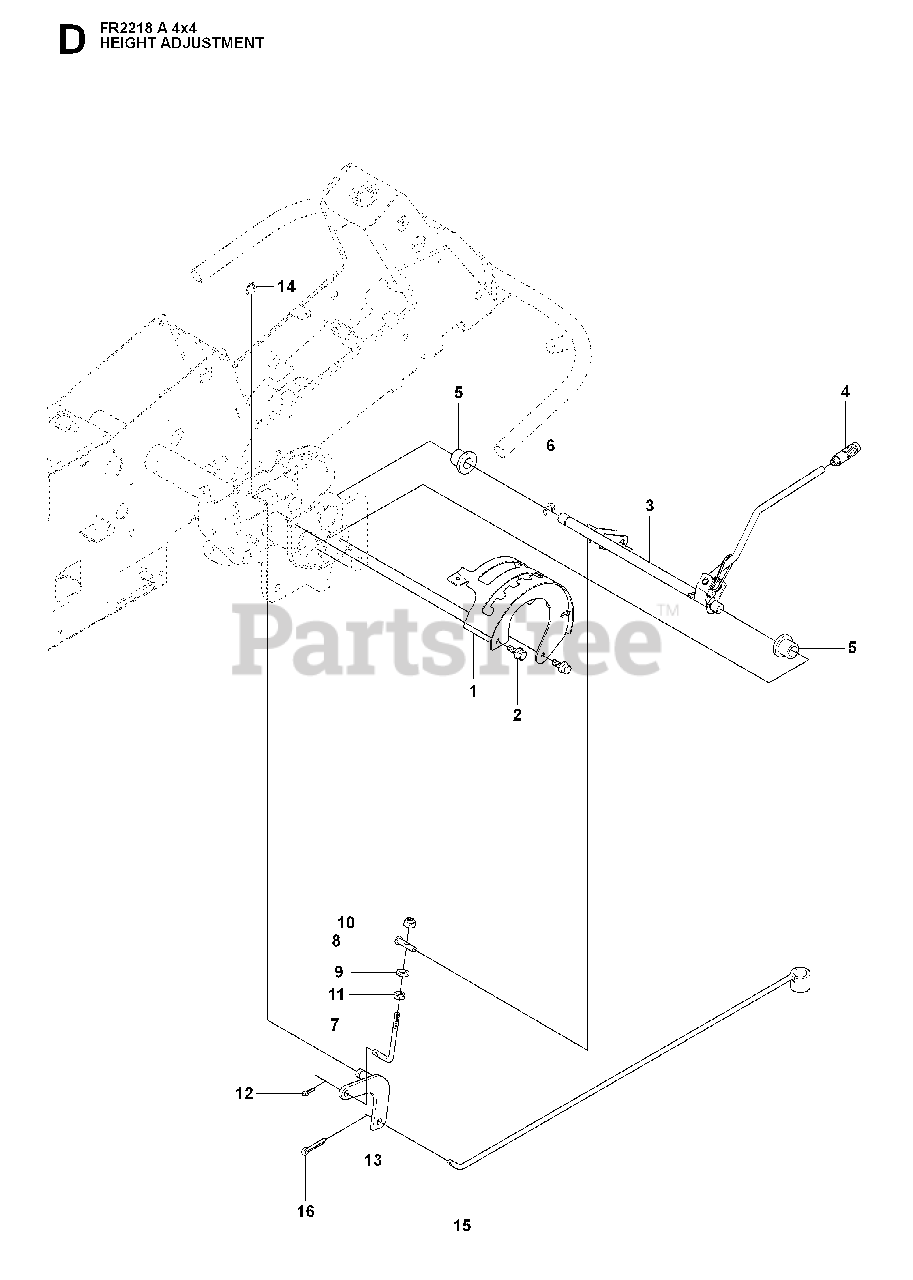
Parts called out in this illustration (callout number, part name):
4	GEAR STICK KNOB
5	BUSHING
9	WASHER
10	LOCKNUT M8
11	NUT
12	SPLIT PIN
14	RETAINING RING
15	CLUTCH ROD
16	SPLIT PIN
